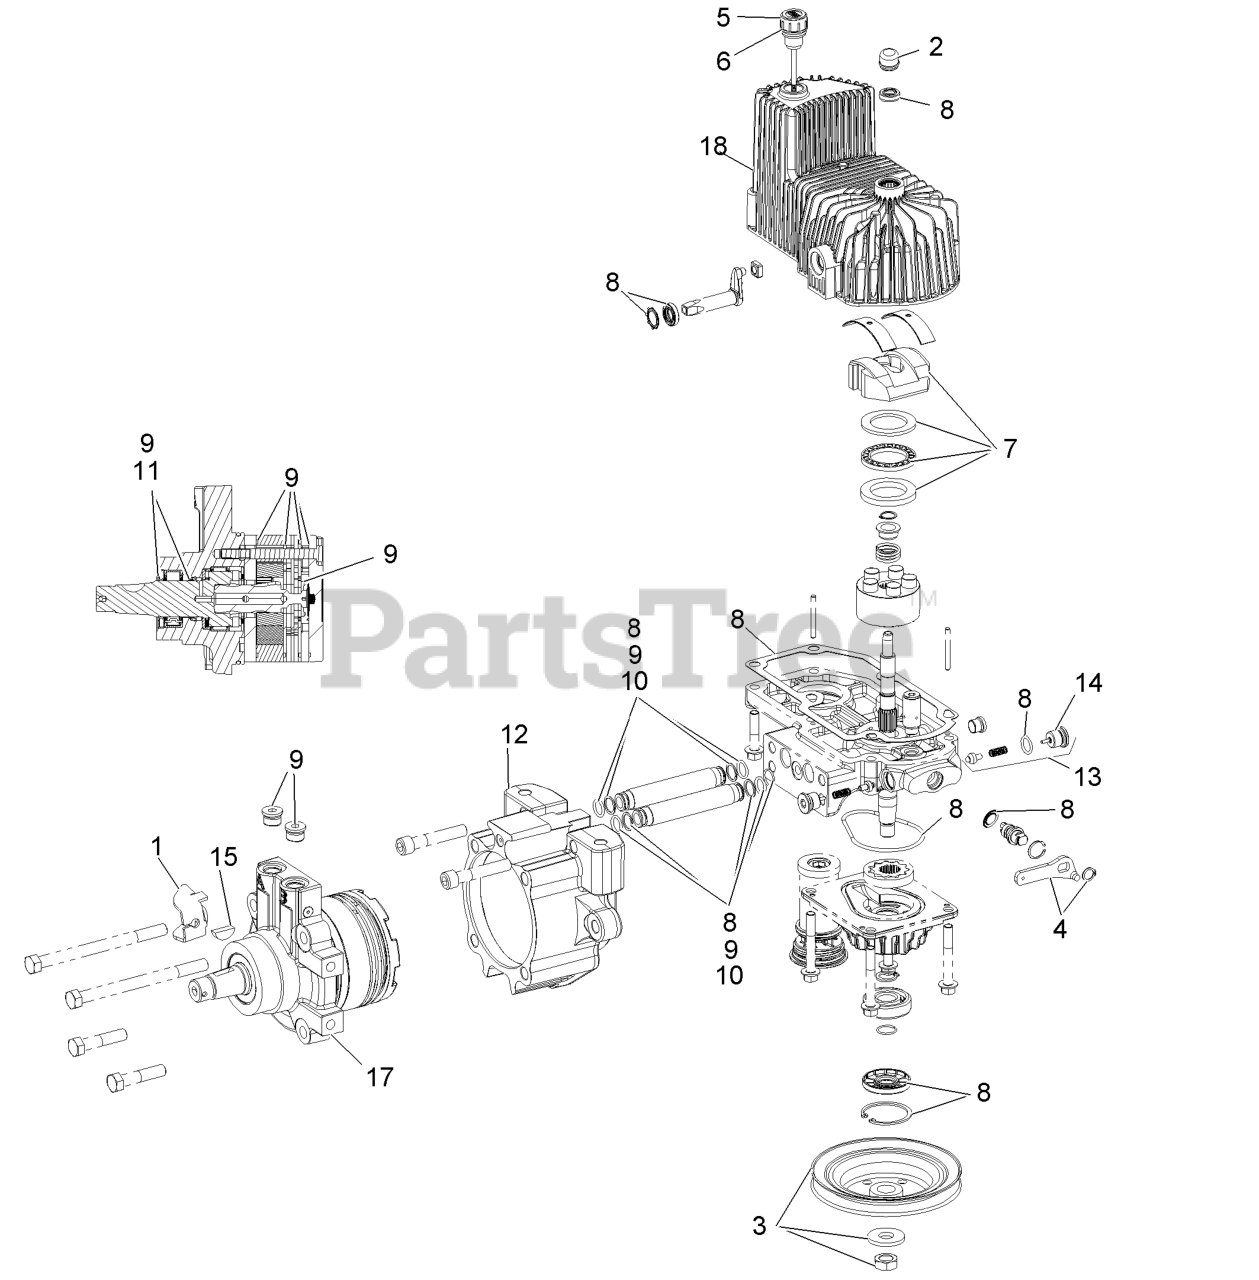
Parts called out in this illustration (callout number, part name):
1	BRACKET-ANCHOR, CABLE
2	COVER-SHAFT, HYDRO
3	PULLEY KIT
4	HANDLE-BYPASS VALVE, HYDRO
5	DIPSTICK-HYDRO W/GASKET
6	GASKET-DIPSTICK, HYDRO
7	SWASH BLOCK KIT
8	PUMP SEAL KIT
9	MOTOR SEAL KIT
10	TUBE SEAL KIT
11	OUTPUT SHAFT SEAL KIT
13	CHECK VALVE ASM
14	PLUG-CHECK (W/O-RING)
15	KEY-WOODRUFF
18	HOUSING-HYDRO, RH
